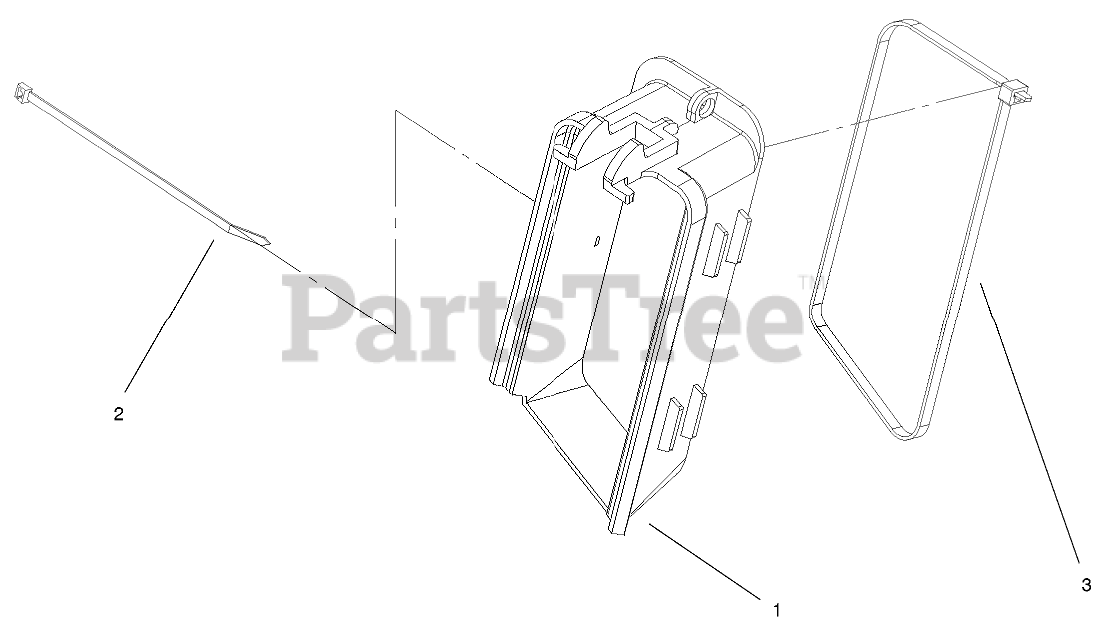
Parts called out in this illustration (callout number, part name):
1	Chute-Bag,Inlet
2	TIE-CABLE
3	STRAP-TIE
